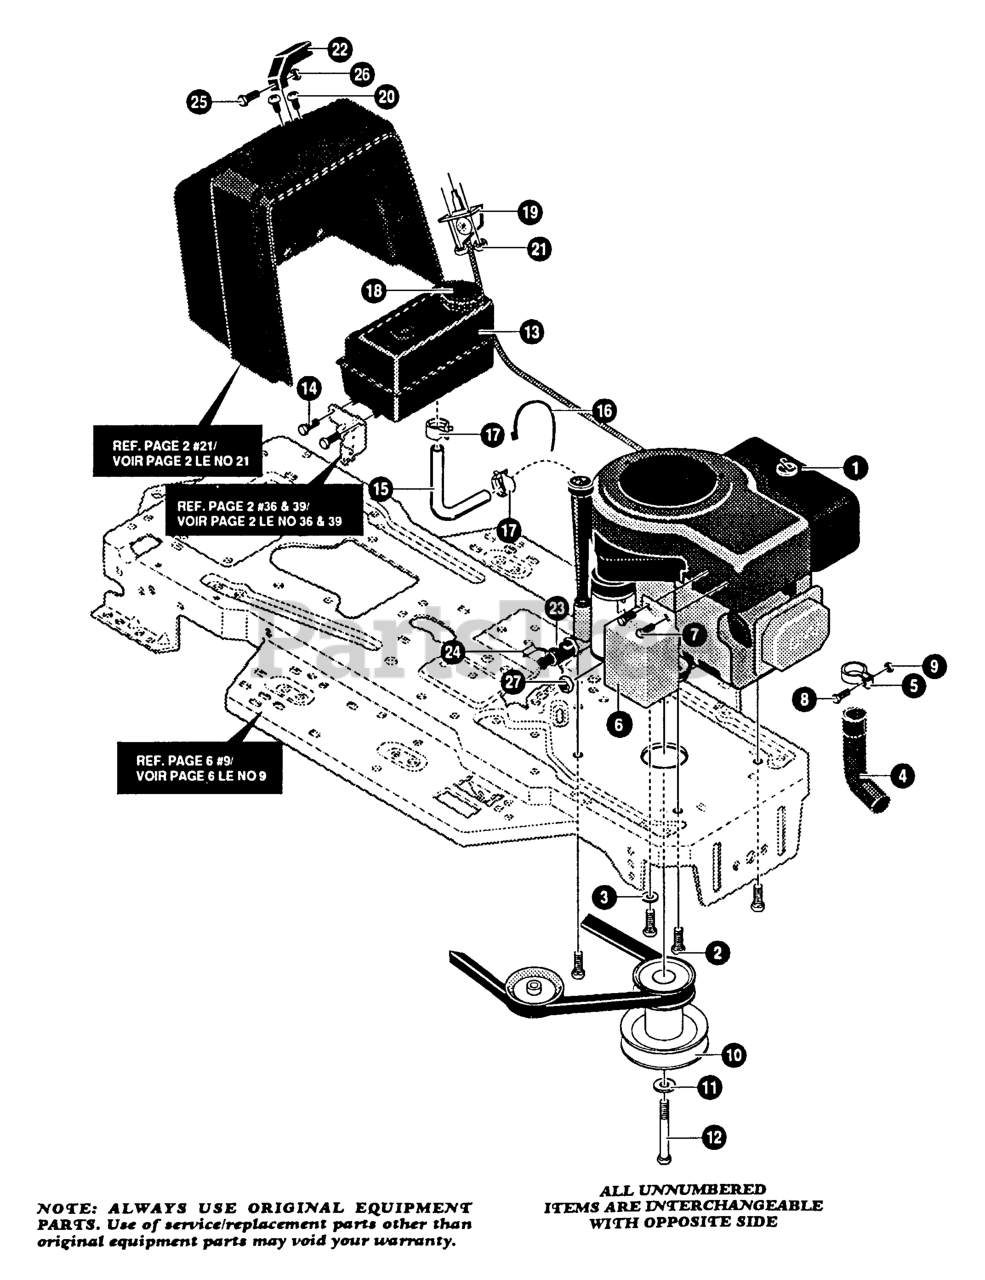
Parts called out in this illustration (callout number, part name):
1	ENGINE *
2	SCREW
4	EXHAUST TUBE
5	CLAMP EXHAUST
6	HEAT SHIELD
10	PULLEY, ENGINE
11	WASHER
13	TANK, FUEL
15	TUBING, GAS LINE
16	TIE, CABLE
17	CLAMP
18	CAP, FUEL
19	THROTTLE
23	OIL DRAIN ASSY
24	CAP, OIL DRAIN
